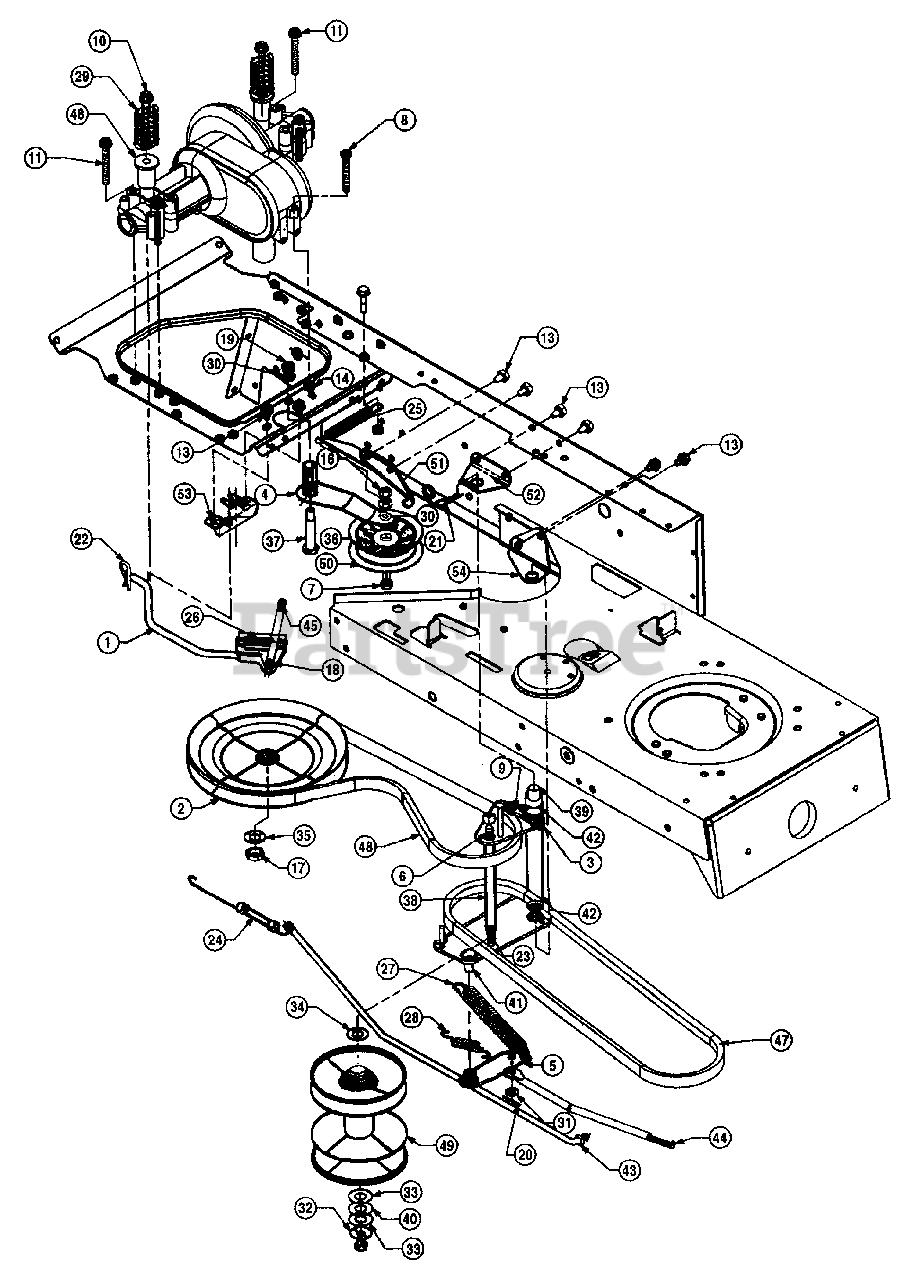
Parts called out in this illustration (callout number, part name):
1	Shift Lever Ass'y.
2	"V"-Pulley
3	Speed Brkt. Ass'y.
4	Idler Brkt. Ass'y.
5	Torque Brkt. Ass'y.
6	Variable Speed Brkt. Ass'y.
7	Hex Bolt 3/8-24 x 2.25" (Gr. 5)
8	Hex Bolt 5/6-18 x 2.25" Leg.
9	Hex Tap Scr. 1/4-20 x .5" Lg.
10	Hex TT-Tap Scr. 3/8-16 x 2.5"
11	Hex Tap Scr. 5/16-18 x 2.5" Lg.
13	Hex SF-Tap Scr. 5/16 x .5" Lg
14	Hex Ctr. L-Nut 5/16-18 Thd.
16	Hex Jam L-Nut 3/8-24 Thd.
17	Hex Jam Nut 9/16-18 Thd. (Gr. 5)
18	Hex Sems L-Nut #10-24 Thd.
19	Hex Nut 3/8-16 Thd. (Gr. 8)
20	Cotter Pin 3/32" Dia. x 1" Lg.
21	Hairpin Clip
22	Hairpin Clip
24	Ext. Spring 7.08" Lg.
25	Ext. Spring 4.74" Lg.
26	Comp. Spring 1.5" Lg.
27	Ext. Spring 7.57" Lg.
28	Ext. Spring 2.54" Lg.
29	Comp. SPring 2.3" Lg.
30	L-Wash. 3/8" I.D.
31	FL-Wash. 5/16" I.D.
32	Bell-Wash. .39" I.D. x 1.13" O.D.
33	FL-Wash. .56" I.D. x 1" O.D.
34	FL-Wash. .565" I.D. x 1.12" O.D.
35	Bell-Wash. .567" I.D. x 1-1/8"
36	FL-Wash. .411" I.D. x .812" O.D.
37	Shld. Bolt .5" Dia. x .433"
38	Shaft 6.92" Lg.
39	Shaft 8.62" Lg.
40	Thrust Brg. .56" I.D.
41	Nyliner Flange Brg.
42	Flange Brg. .63" I.D.
43	Brake Rod
44	Speed Control Link
45	Shift Lever
47	"V"-Belt
48	"V"-Belt
49	Variable Speed Pulley
50	Flat Idler Pulley
51	Retainer Spring
52	Support Brkt.-Upper
53	Retainer-Shift Lever
54	Support Brkt.-Lower
